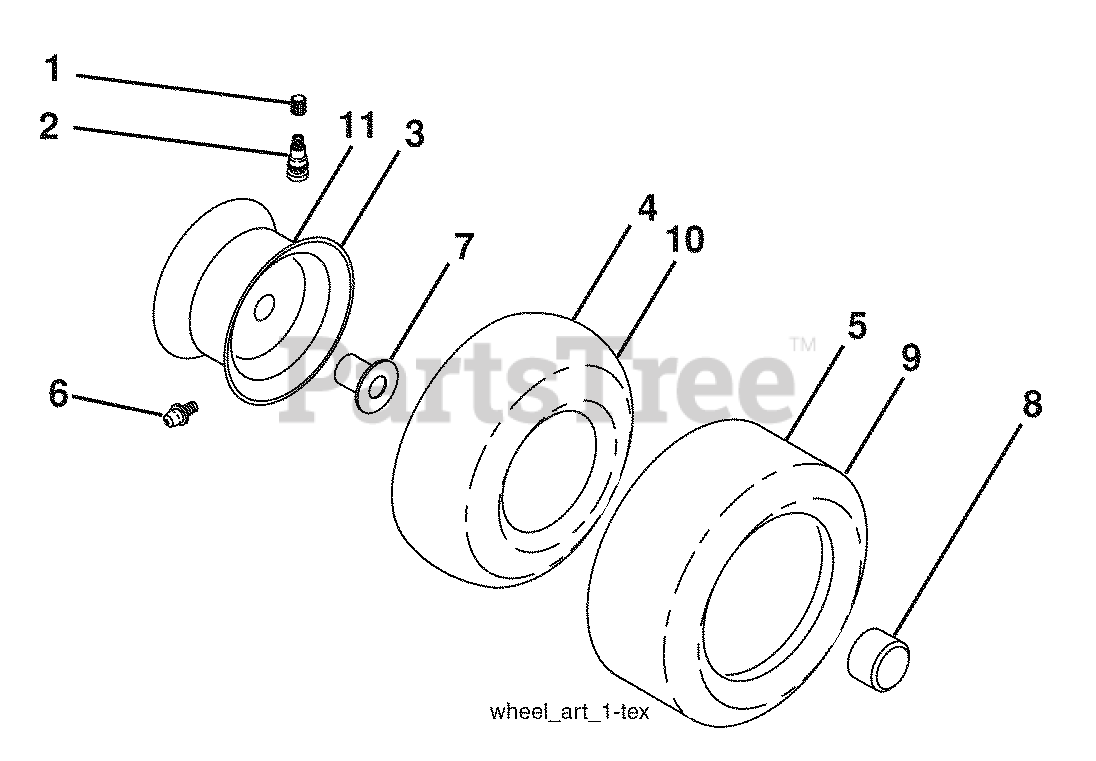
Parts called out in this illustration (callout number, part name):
1	Cap Valve Tire
2	Stem Valve
3	Tire F T 15 x 6 0 - 6 Service
4	Tube Front
5	Rim Asm 6" front Service
6	Fitting Grease
7	Bearing Flange
8	Cap Axle Blk 1 50 x 1 00
9	Tire R T 18 x 9.5-8 Service
10	Tube Rear
11	Rim Asm 8" rear Service
